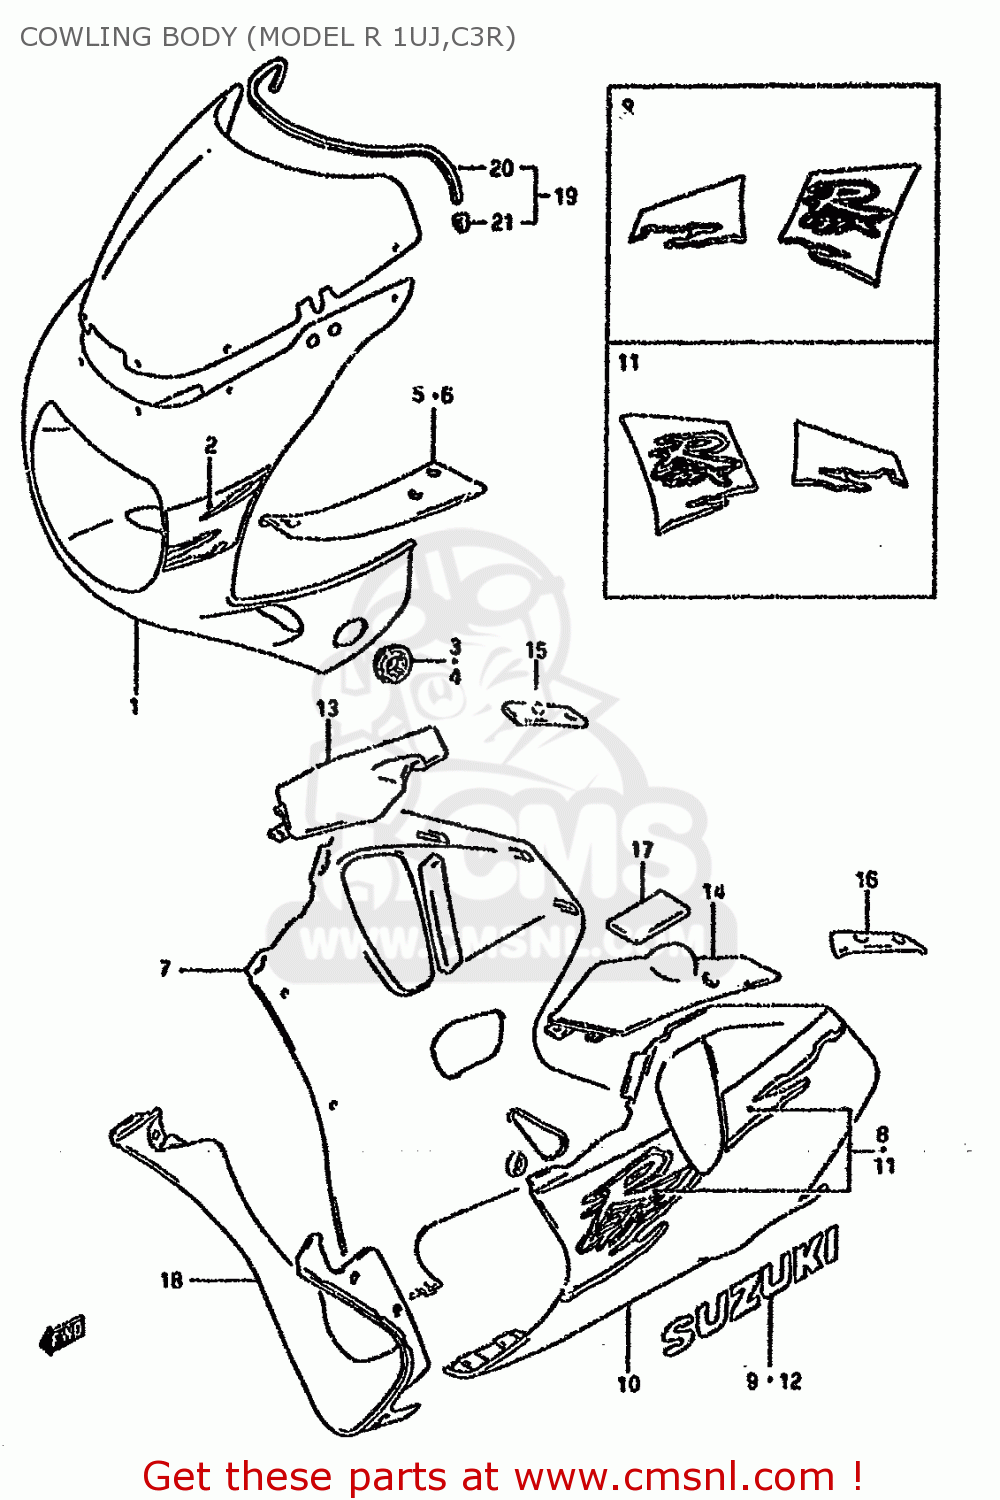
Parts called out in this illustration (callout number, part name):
1	COWLING ASSY,BODY
2	TAPE SET,COWL BODY
3	PLATE,TURN SIGNAL,RIGHT
4	PLATE,TURN SIGNAL,LEFT
5	PANEL,COWLING,UPPER,RIGHT
6	PANEL,UPPER,LEFT
7	COWLING ASSY,UNDER,R
8	TAPE SET,COWL UNDER,R
9	EMBLEM,SUZUKI
10	COWLING ASSY,UNDER,L
11	TAPE SET,COWL UNDER,L
12	EMBLEM,SUZUKI
13	PANEL,LWR FR,R
14	PANEL,LWR FR,L
15	PANEL,LWR RR,R
16	PANEL,LWR RR,L
17	CUSHION,PANEL
18	COWLING,UNDER CTR
19	WINDSCREEN SET
20	MOLDING WINDSCREEN
21	CLIP,WINDSCREEN MOLDING
